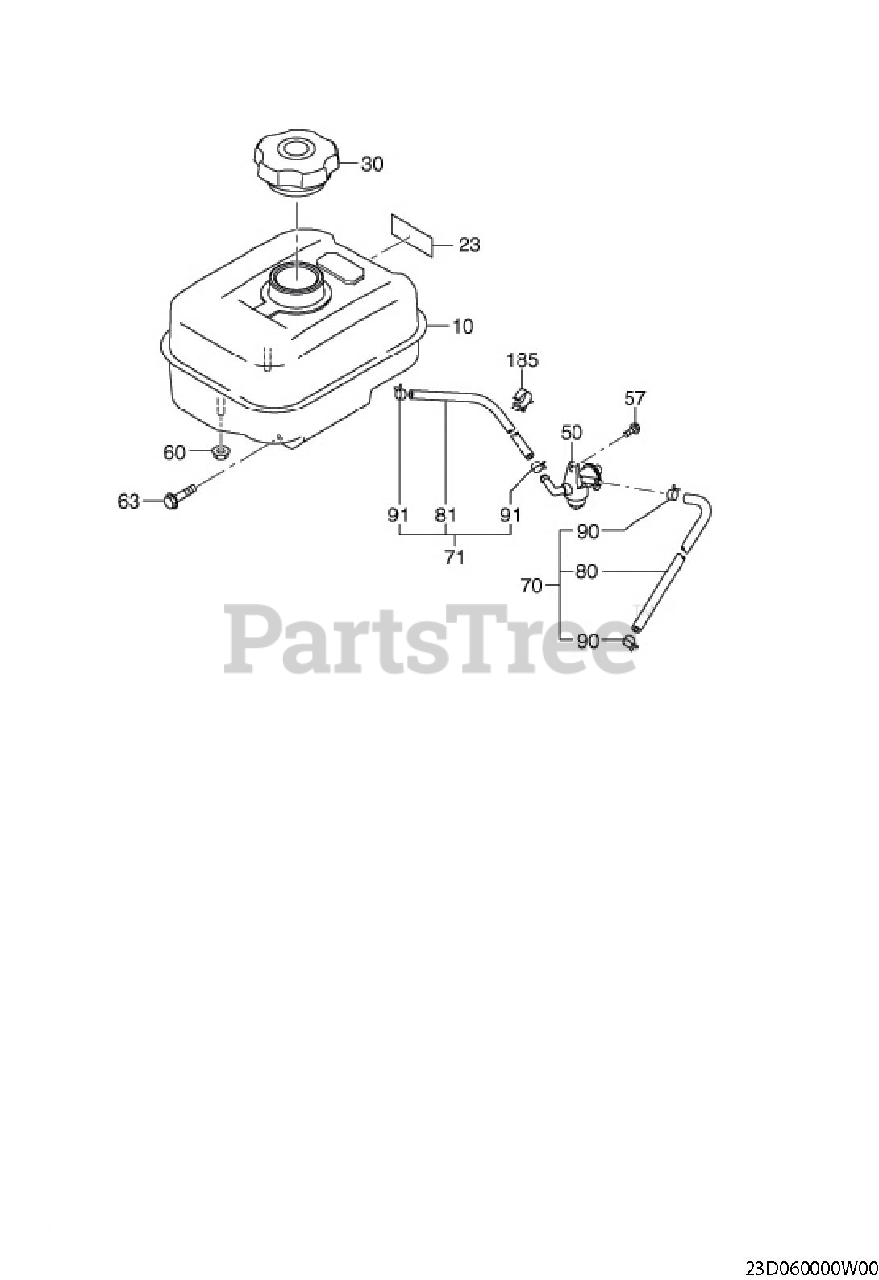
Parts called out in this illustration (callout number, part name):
23	LABEL(MODEL)
30	FUEL TANK CAP CP
50	FUEL STRAINER AY
57	FLANGE BOLT
60	FLANGE NUT
63	FLANGE BOLT
70	FUEL PIPE CP
71	FUEL PIPE CP
80	RUBBER PIPE
81	RUBBER PIPE
90	HOSE CLAMP
91	HOSE CLAMP
